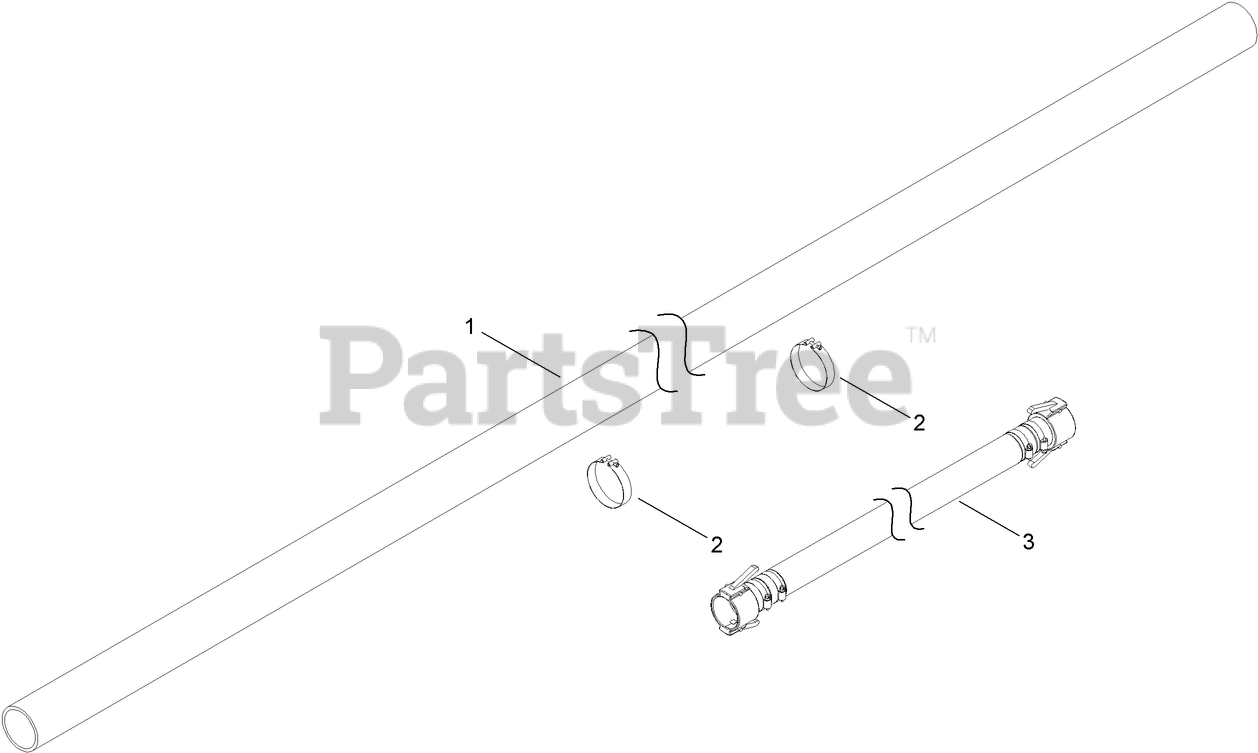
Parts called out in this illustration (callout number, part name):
1	HOSE-SUCTION, WATER
2	CLAMP-T BOLT
3	DISCHARGE HOSE ASM
